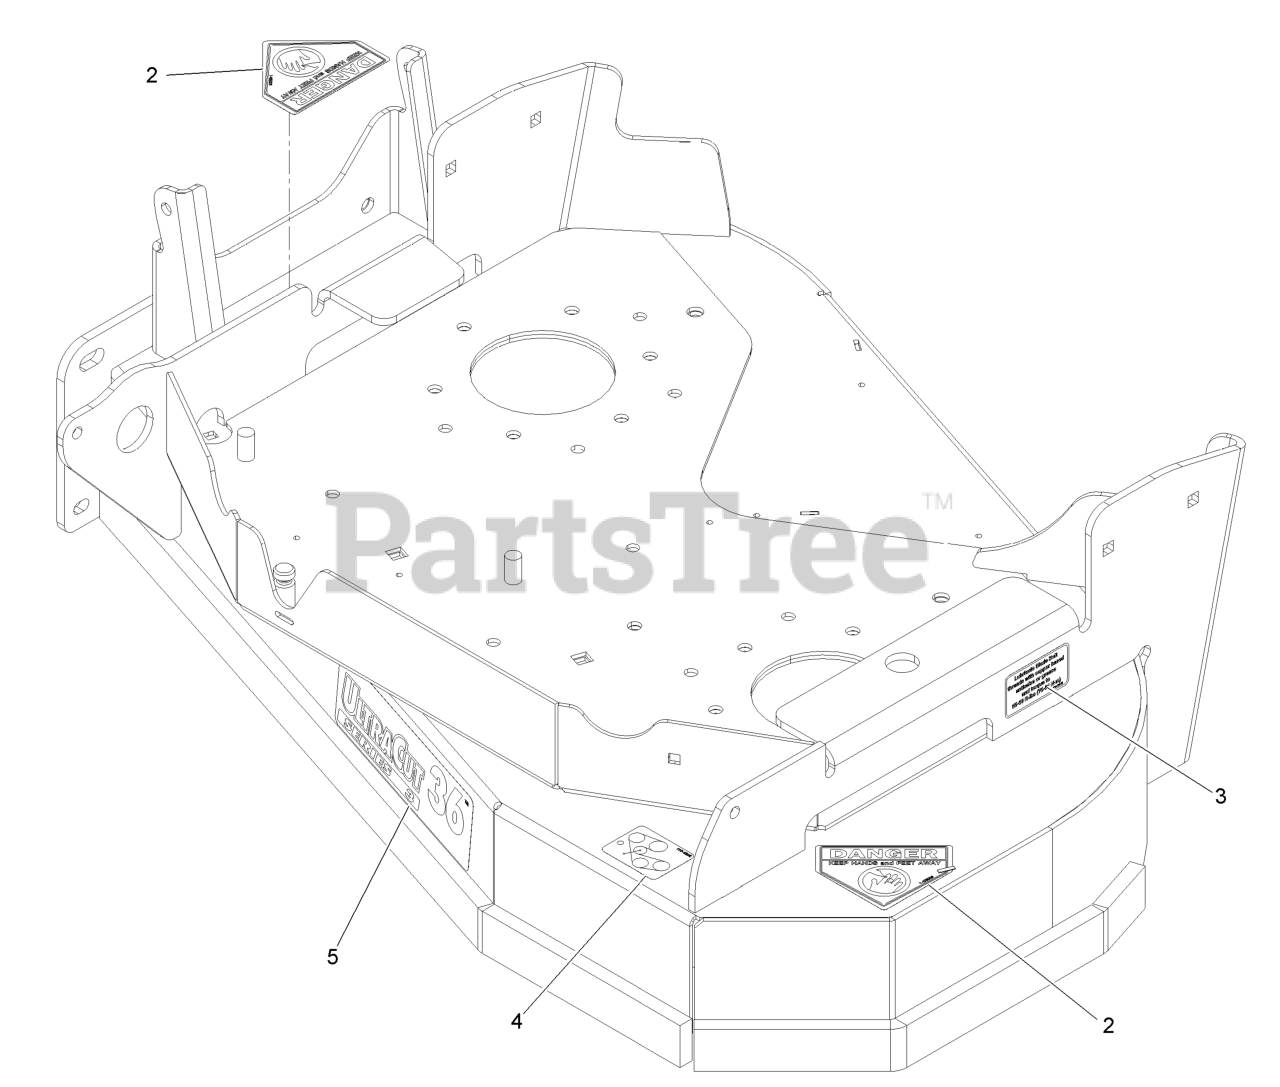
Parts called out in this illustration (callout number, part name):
2	DECAL-DANGER
3	DECAL,BOLT TORQUE
4	DECAL-BELT ROUTING 36
5	DECAL-ULTRACUT 36 SERIES
